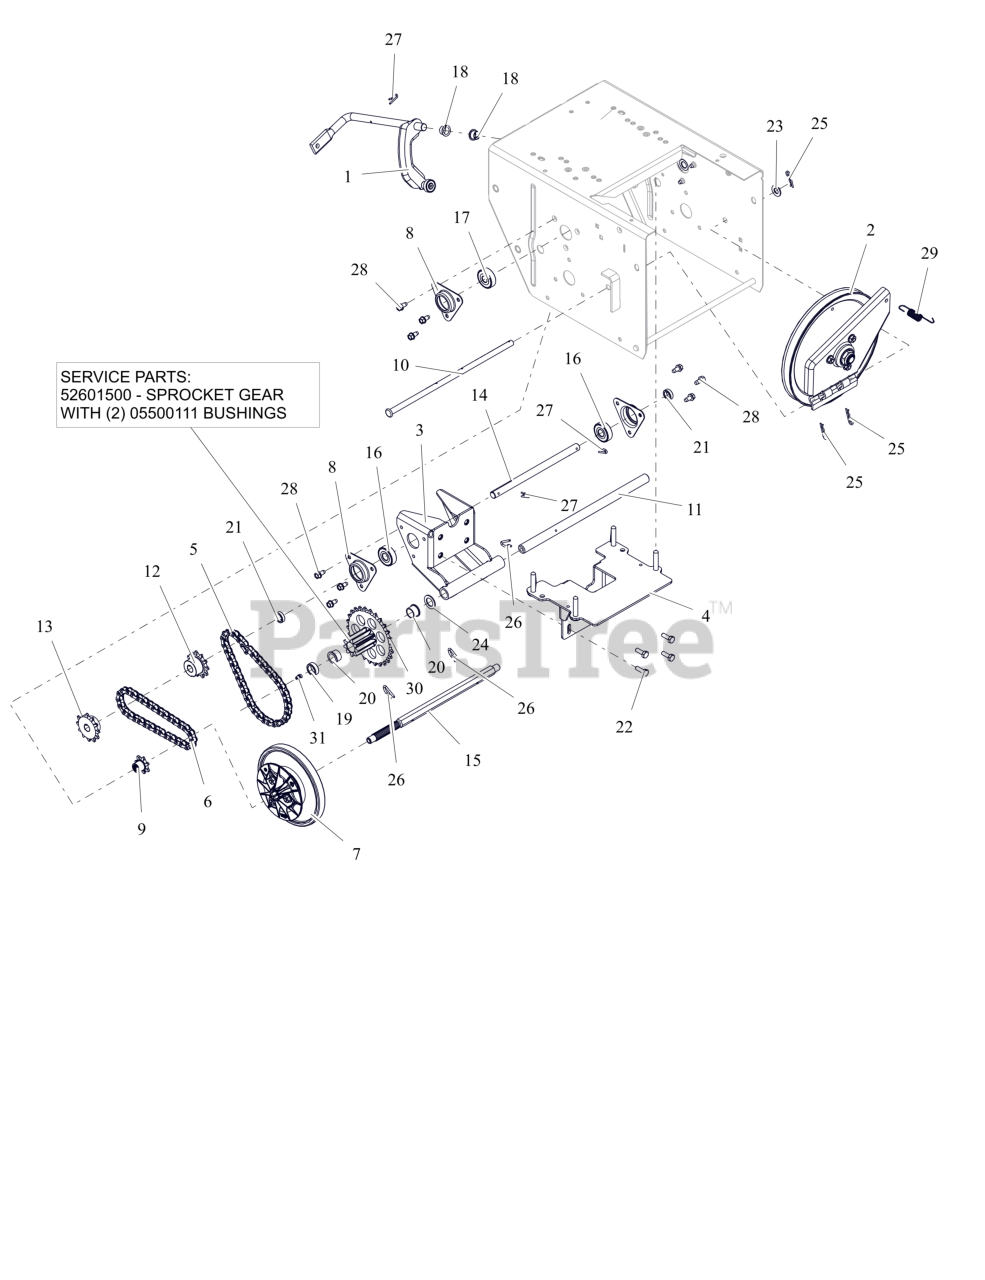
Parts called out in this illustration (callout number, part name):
1	ARM, SHIFT - ASSEMBLY
2	PLATE, SWING ASSEMBLY-DEEP
3	WLDMT, TRIPLE REDUCTION BRKT
4	STRAP, TRIPLE REDUCITON BOLT
5	CHAIN, ROLLER - #41X36 PITCHES
6	CHAIN - #41, 32 PITCHES
7	DISC, FRICTION DRIVE-ASSEMBLY
8	FLANGE, BEARING
9	SPROCKET, PINION 7T W/SPLINE
10	PIN, PIVOT
11	SHAFT, PINION-HARDENED
12	SPROCKET, 11 TOOTH
13	SPROCKET, 12 TOOTH
14	SHAFT, REDUCTION HEAT TREATED
15	SHAFT, HEX HEAT TREATED SPLINE
16	BRG-BALL .500X1.38X.437
17	BRG-BALL .437X1.375X.437
18	BUSHING, POLYLINER-.50 SPLIT
19	BSHG-SLV, .635X.880X.305
20	BSHG-FLG .625X.750X.500X.875
21	SPCR, SLV
22	BLT, HEX .25-20X.75 G5 ZCC
23	WSHR,FLT .406X.812X.065 ZCC
24	WSHR, FLT .630X1.005X.062 ZCC
25	PIN, HAIR #213 .08X1.19 ZCC
26	PIN, SPRING CLIP
27	CLIP, SPRING
28	SCR-TAP .25-20X.50 HWH ZCC
29	SG-TENS .048X.50X2.8
30	PINION & SPROCKET
30	PINION & SPROCKET W/BUSHINGS
31	ZERK,FITTING .25X.125 DRIVE IN
